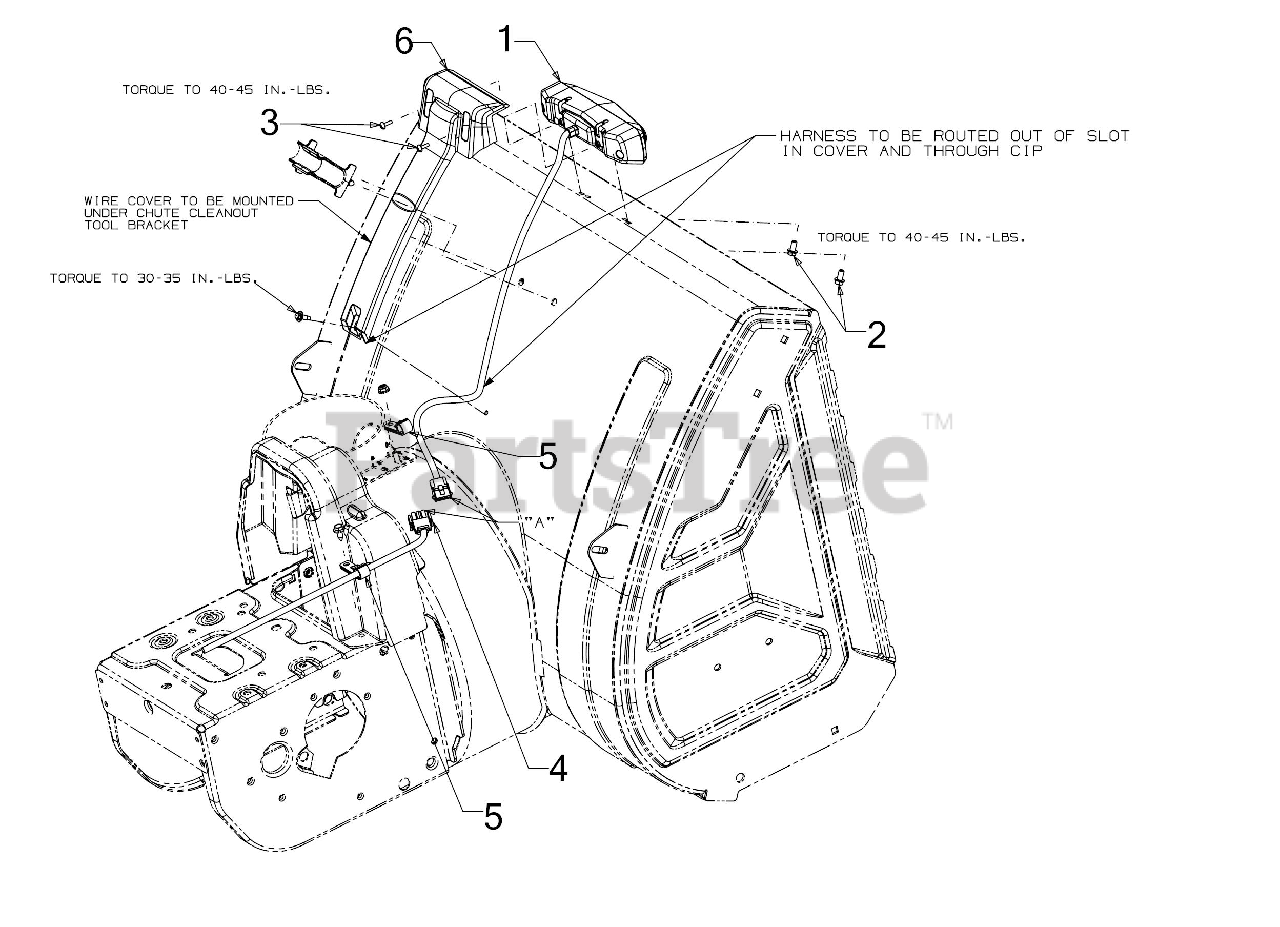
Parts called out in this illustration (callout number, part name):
1	LED LIGHT BAR HEADLIGHT ASSEMBLY
2	HEX SCREW 1/4-15 x .50
3	SCREW 8/16X.500
4	LED HEADLIGHT HARNESS
5	HEADLIGHT HARNESS CLAMP
6	LED LIGHT BAR COVER
